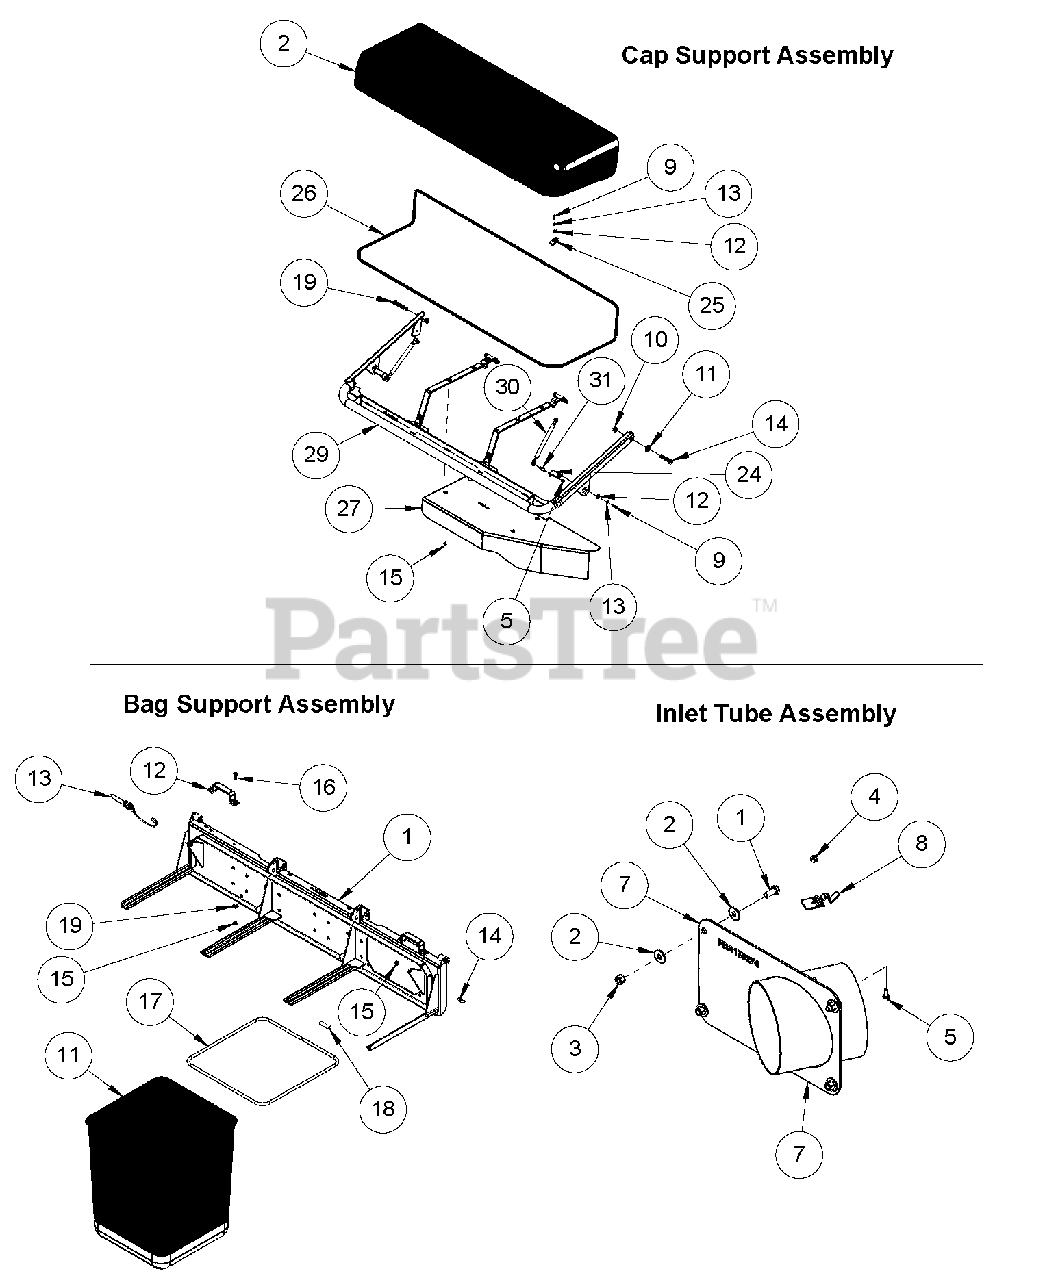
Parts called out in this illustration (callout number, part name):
1	Catcher Bag, Commercial
2	Generic Air Dome (3-Bag) Extended
3	1.5" Hole Plug, Plastic
4	Cap Screw 5/16- 18 X .75
5	5/16-18 Nylon Insert Nut
6	5/16" Flat Washer
7	1/2 Detent Pin 2.5" Kibg
8	Rubber Bumper
9	Cap Screw 1/4-20 X .75
10	1/2-13 Nylon Insert Nut
11	1/2" Flat Washer
12	1/4" USS Washer
13	1/4" Lockwasher
14	CS 1/2-13 X 2.5 G5
15	1/4-20 X 1/2 G5
16	#10 X 1/2" Screw
17	#10-24 Nylon Insert Nut
18	Spring Clip
19	CS 1/2-13 X 3 G5
20	Tube, Plastic 1/2" OD X 3/8 ID
21	Bag Handle
22	Inlet Tube (Short)
23	Bag Frame
24	Gas Cylinder Mount
25	Bracket Mount
26	Air Dome Frame (3-Bag)
27	3 Bag Deflector
28	3-Bag Support Mount
29	3 Bag Raised Cap Support
30	Gas Cylinder, 6X15 LOM 375 EXT
31	Ball Joint
